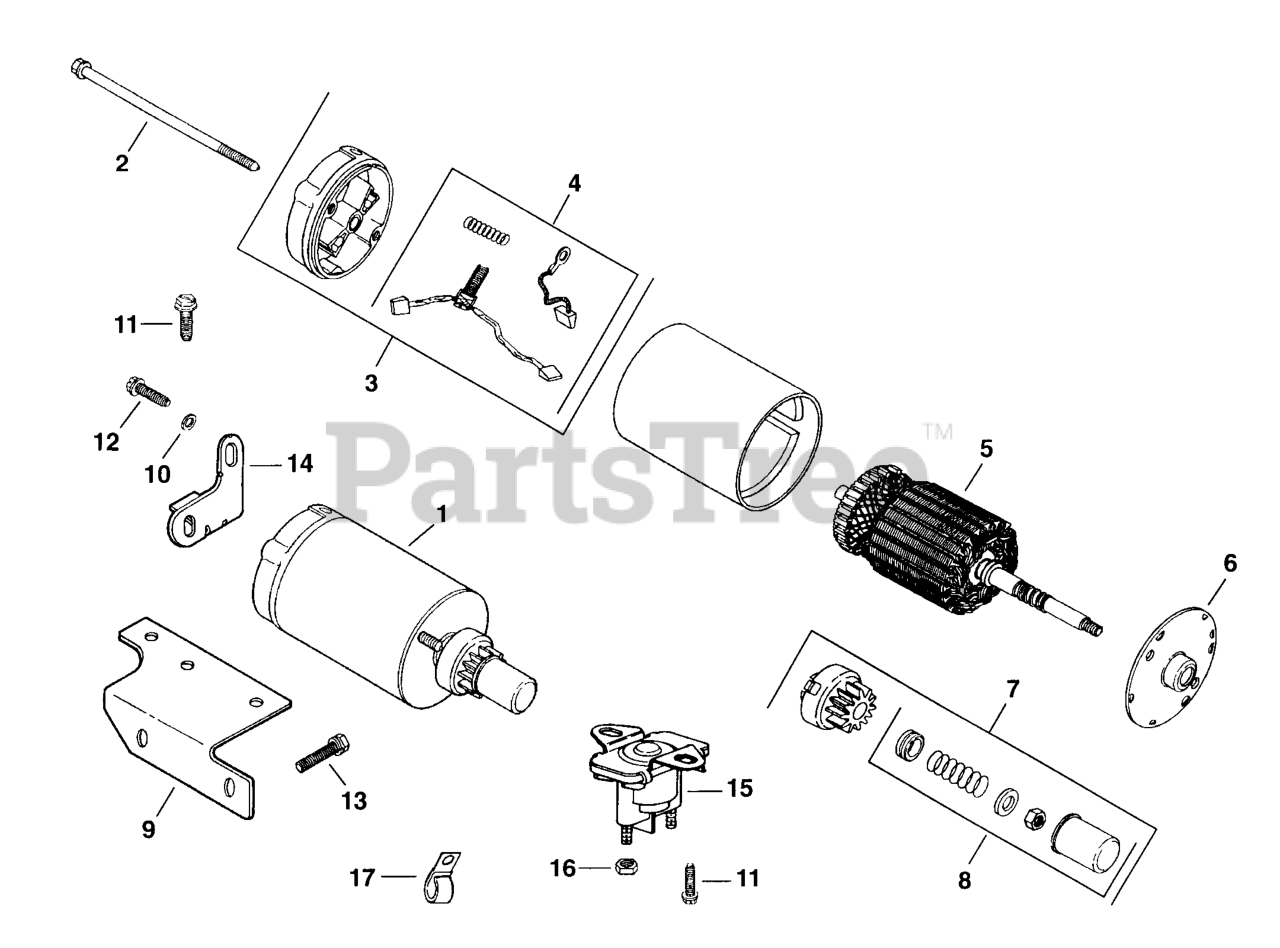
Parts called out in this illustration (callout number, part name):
1	STARTER - USE 41 098 06
2	BOLT, STARTER 1/4-20X5-1/16"-(#DSC)
3	CAP - DISCONTINUED
4	KIT - USE 82 755 28
5	ARMATURE - DISCONTINUED
6	CAP - USE 41 081 05
9	BRACKET-(#DSC)
11	SCREW, WSH HD TAP 1/4-20X3/4" USE 25 086 100-S
12	SCREW, WSH HD TAP 1/4-20X7/16" USE 25 086 106-S
13	SCREW, SEMS 3/8-16-X1"
14	BRACKET, SOLENOID
5235701-S	Lubricant, Inertia Drive Starter (0.25 oz.)
